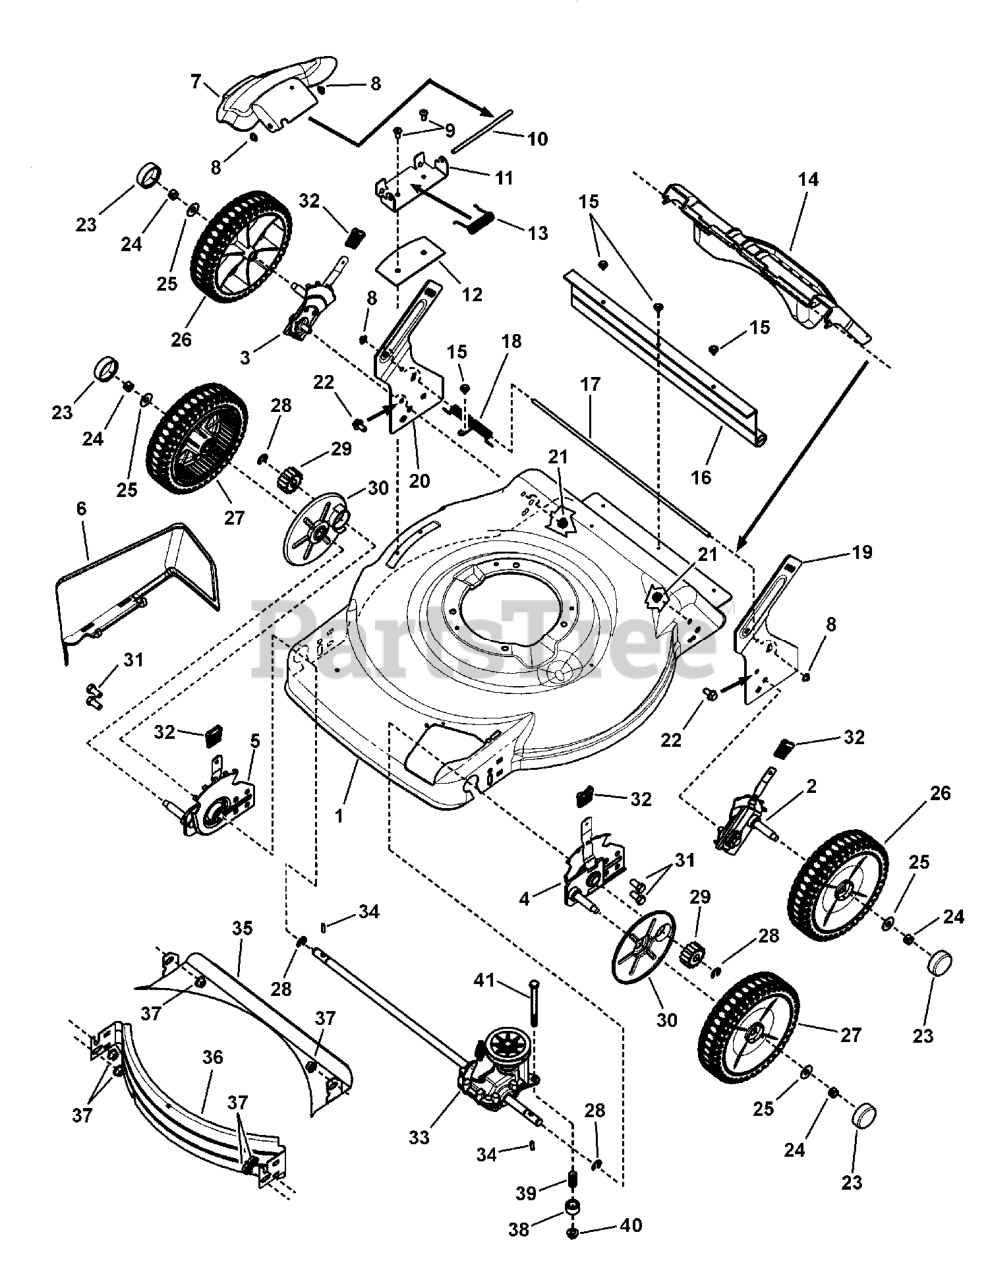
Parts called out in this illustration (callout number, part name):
1	DECK, 22" Walk, 3-N-1
2	ASSEMBLY, Height-Of-Cut, Left Rear
3	ASSEMBLY, Height-Of-Cut, Right Rear
4	ASSEMBLY, Height-Of-Cut, Left Front
5	ASSEMBLY, Height-Of-Cut, Right Front
6	SIDE CHUTE, Plastic, Black
7	COVER, Mulch, Plastic, Black
8	PUSHNUT, 1/4"
9	SCREW, 1/4-20 x .550 Pan Head Self-Tap (Torx)
10	ROD, Chute Pivot (1/4" Dia. x 5.55")
11	BRACKET, Chute
12	PLATE, Mulch, 22" RB Scott's
13	SPRING, Chute (Torsion)
14	DOOR, 22" Rear
15	SCREW, #10-24 x 1/2" Hex Washer Self-Tap (Sems)
16	GUARD, Rear, 22" WBM
17	ROD, Pivot, Rear Door
18	SPRING, Torsion, Rear Door, 22" Walk Mower
19	BRACKET, Lower Handle, LH
20	BRACKET, Lower Handle, RH
21	NUT, 5/16-18 Flange Lock, YZ
22	BOLT, 5/16-18 x 5/8" Hex Flange Lock, GR 5 YZ
23	HUBCAP, Round, Black
24	NUT, 3/8-16 Hex Center Lock, YZ
25	WASHER, 1" O.D. x .387 I.D. Flat
26	WHEEL, 8" x 2" Idle, w/Db Tread, Brute Yellow
27	WHEEL, 8" x 2" Drive, w/Db Tread, Brute Yellow
28	RING, External Retaining
29	GEAR, Pinion, 22" WBM, FWD
30	SHIELD, Dust, 22" WBM, FWD
31	SCREW, 3/8-16 x 3/4" Hex Head Cap, GR 5
32	GRIP, Height Latch, Black
33	TRANSMISSION, 22" WBM SS, FWD
34	DRIVE PIN, 22" WBM, Front Wheel Drive
35	BAFFLE, Rear, 22" Deck
36	BAFFLE, Front, 22" WBM
37	NUT, 3/8-16 Hex Flange Lock, GR 5
38	SPACER, Drive Transmission
39	SPRING, Compression
40	NUT, 5/16-18 Hex Flange Lock
41	SCREW, 5/16-18 x 3" Hex Head Cap
